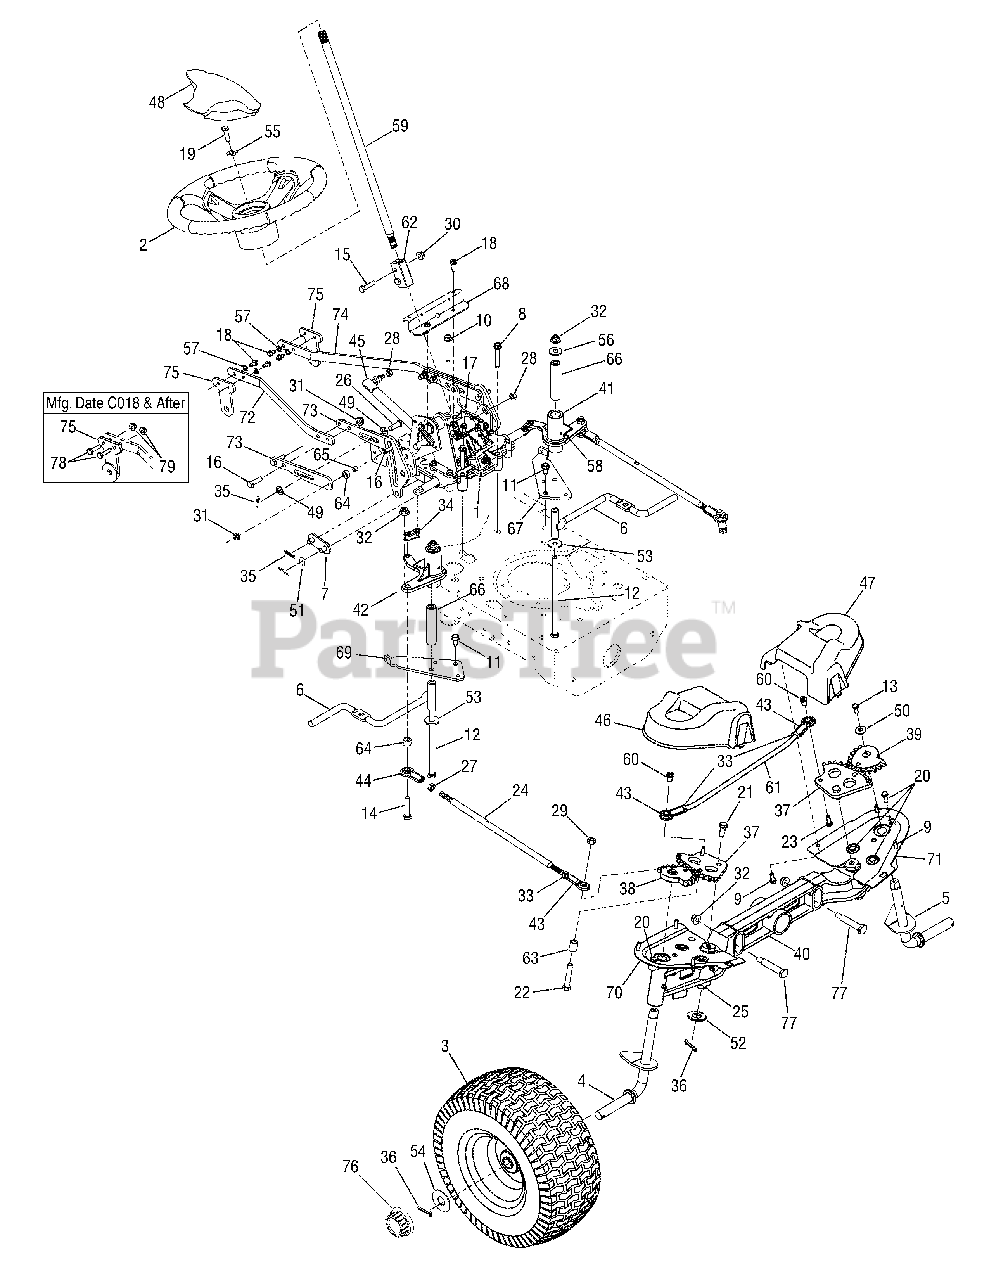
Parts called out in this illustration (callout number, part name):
1	Steering Assembly, Steering/Hydro
1	Kit, Replacment Steering Gear Box
2	Wheel, Steering
3	Wheel Assembly
7	Link, Steering Box/Hydro
8	Screw, Hex Wash Hd. Tapp, 5/16-18 x 2.0
9	Screw, Hex Wash Hd. Hi/Lo, 1/4-15 x .5
10	Screw, Hex Wash Hd. Tapp, 5/16-18 x 2.25
11	Screw, Hex Wash Hd. Tapp, 5/16-18 x .75
12	Screw, Hex Cap, 3/8-16 x 7.25 Gr5
13	Screw, Hex Cap Lock, 1/4-28 x .625 Gr5
14	Screw, Hex Cap, 3/8-16 x 1.5 Gr5
15	Screw, Hex Cap, 5/16-18 x 1.25 Gr5
16	Screw, Hex Cap, 1/4-20 x 1.0 Gr5
17	Screw, Hex Wash Hd. Tapp, 1/4-20 x .5
18	Screw, Hex Wash Hd. Tapp, 1/4-20 x .75
19	Screw, Hex Wash Hd. Tapp, 5/16-18 x .875
20	Screw, Hex Cap, 1/4-20 x .75 Gr5
21	Screw, Hex Cap Lock, 3/8-16 x .75 Gr5
22	Screw, Hex Cap, 3/8-16 x 2.0 Gr5
23	Screw, Hex Cap Lock, 1/4-20 x .75 Gr5
24	Link, Drag
25	Shaft, Steering Pivot Gear
26	Pin, Clevis, .375 x .969 HT
27	Nut, Jam, 3/8-24 LH Thrd
28	Nut, Hex Lock, M8 x 1.25 Gr9
29	Nut, Hex Lock, 3/8-16
30	Nut, Hex Insert Flange Lock, 5/16-18 GrF
31	Nut, Hex Insert Flange Lock, 1/4-20 GrF
32	Nut, Hex Insert Flange Lock, 3/16-16 GrF
33	Nut, Hex Jam, 3/8-24 Gr2
34	Link, Connnecting
35	Pin, Internal Cotter
36	Pin, Cotter, 5/32 x 1.25
37	Gear, Spur, 12T
38	Gear, Spur, RH 13T
39	Gear, Spur, LH 13T
40	Axle, Pivot Bar
43	End, Ball Joint Rod
44	End, Ball Joint Rod, LH Thrd.
45	Cylinder, Damper
46	Cover, Steering Gear, RH
47	Cover, Steering Gear, LH
48	Cover, Steering Wheel
49	Washer, Flat, .375 x .738.063
50	Washer, Bell, .265 x .75 x .062
51	Washer, Sping, .39 x .75 x .010
52	Washer, Flat, .76 x 1.5 x .12
53	Washer, Bell, .396 x 1.14 x .095
54	Washer, Flat, .755 x 1.92 x .060
55	Washer, Flat, .406 x .875 x .105
56	Washer, Flat, .406 x 1.0 x .105
57	Washer, External Lock, 1/4
58	Fitting, Grease
59	Shaft, Steering, .625 x 17.281
60	Nut, Shoulder, .375 x .5
61	Rod, 3/8-24 x 14.4 Lg
62	Block, Steering Shaft
63	Spacer, .385 x .63 x .75
64	Spacer, .380 x .625 x .265
65	Spacer, .26 x .372 x .33
66	Spacer, .385 x .75 x 3.47
73	Bracket, Hydro/Steering Adjustment
75	Bracket, Steering Link
76	Hub Cap
77	Bolt, Shoulder, .5 x 2.23:3/8-16
78	Screw, Hex Cap, 1/4-20 x 1.0 Gr5
79	Nut, Hex Insert Flange Lock, 1/4-20
